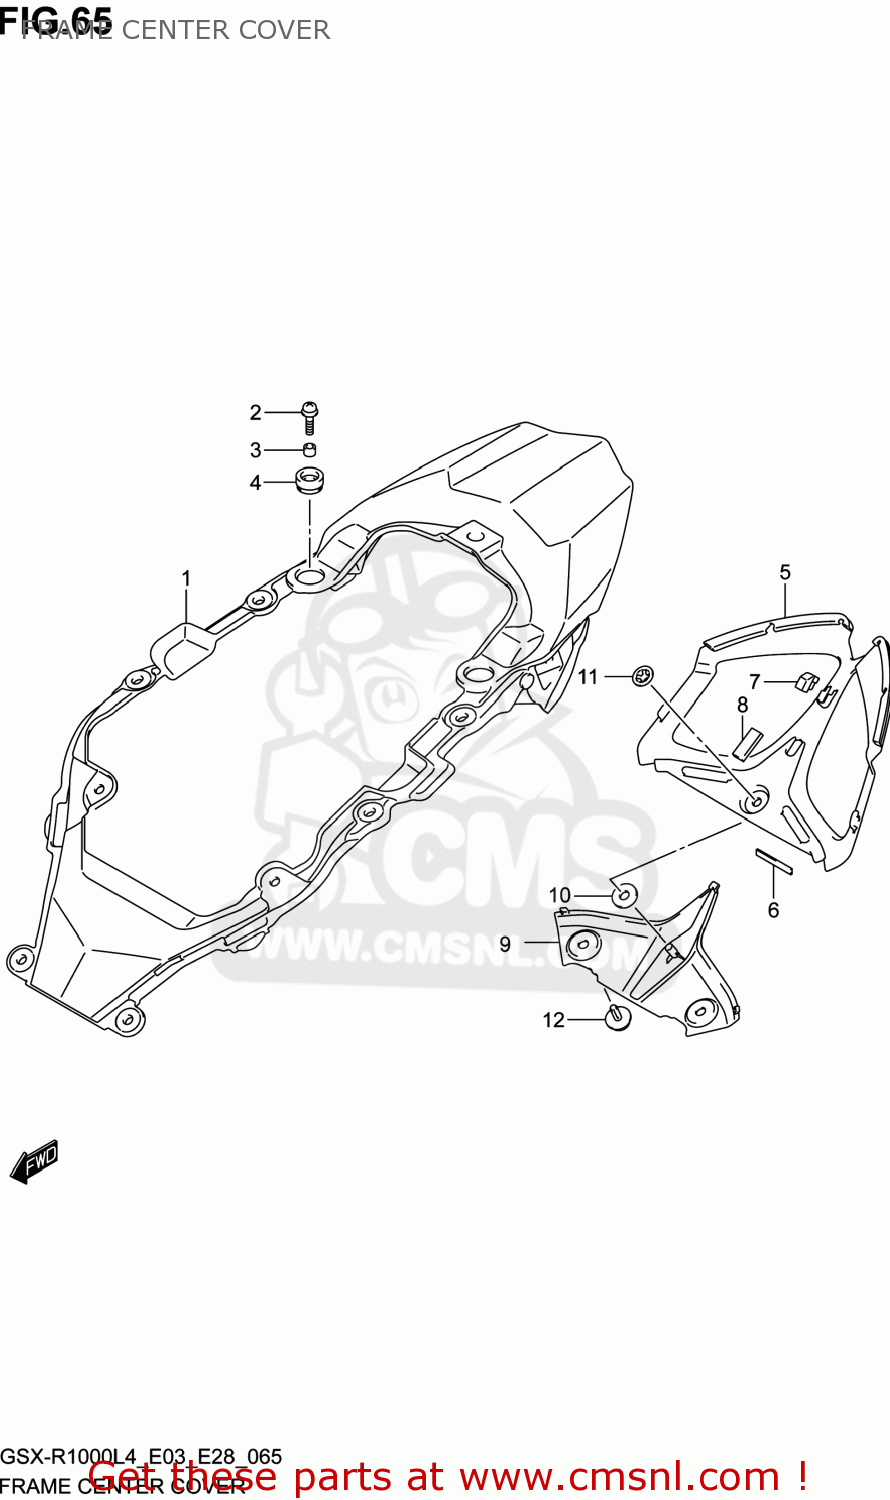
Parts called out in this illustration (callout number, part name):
1	COVER,FRAME CTR
2	SCREW(6X16)
3	SPACER(6.5X10X7)
4	CUSHION,FRAME COVER RR
5	COVER,FRAME RR CTR
6	CUSHION,FRAME COVER RR CTR
7	CUSHION,FRAME COVER RR CTR
8	CUSHION,CTR PANEL UPR
9	COVER,FRAME RR CTR LWR
10	CUSHION
11	NUT
12	CLIP
